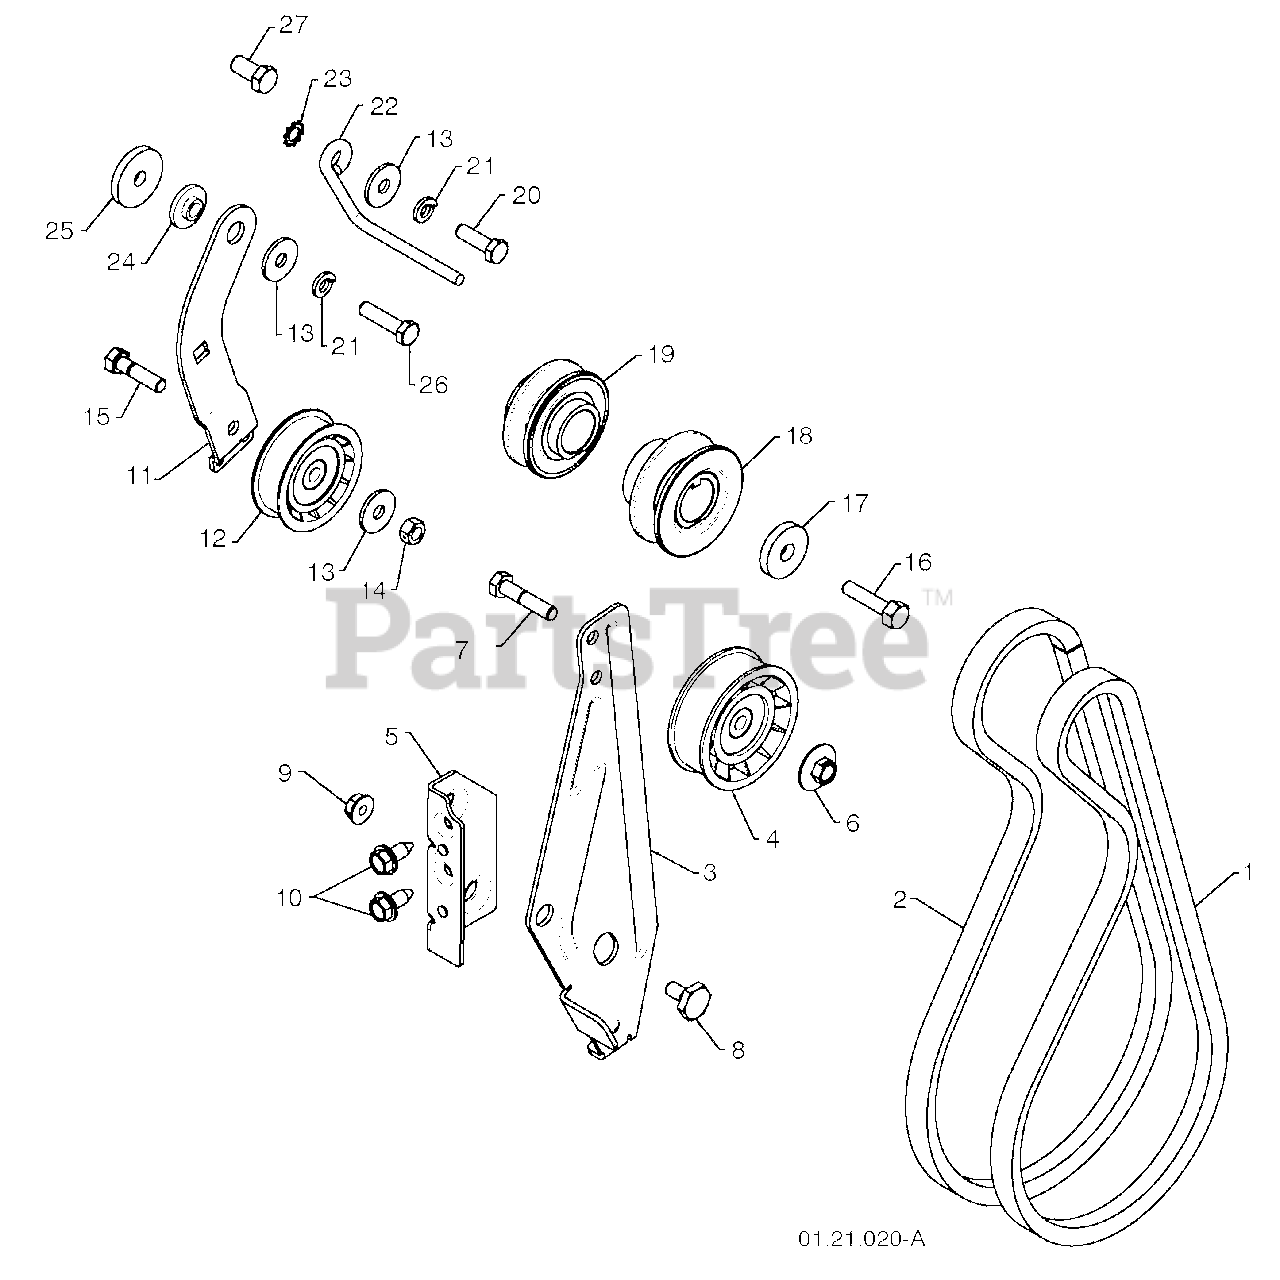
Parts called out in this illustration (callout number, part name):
1	IMPELLER BELT
2	TRACTION BELT
3	IDLER ARM BRACKET
4	IDLER PULLEY
5	IDLER BRACKET
6	NUT 5/16-18
7	SCREW 5/16-18 X 1.50
8	SHOULDER BOLT 5/16-18 X .50
9	NUT 5/16-18 LOCK
10	SCREW 5/16-18 X .625
11	TRACTION IDLER BRACKET
12	TRACTION PULLEY
13	WASHER
14	NUT 5/16-18
15	SCREW 5/16-18 X 1.25
16	SCREW 3/8-24 X 1 .375
18	PULLEY ENG IMPELLER
19	PULLEY ENG TRACTION
20	SCREW 5/16-24 X 1.00
21	LOCKWASHER 5/16
22	BELT GUIDE
23	LOCKWASHER 5/16
24	IDLER BUSHING
25	WASHER
26	SCREW 5/16-24 X 1.25
27	SCREW 3/8-16 X .750
